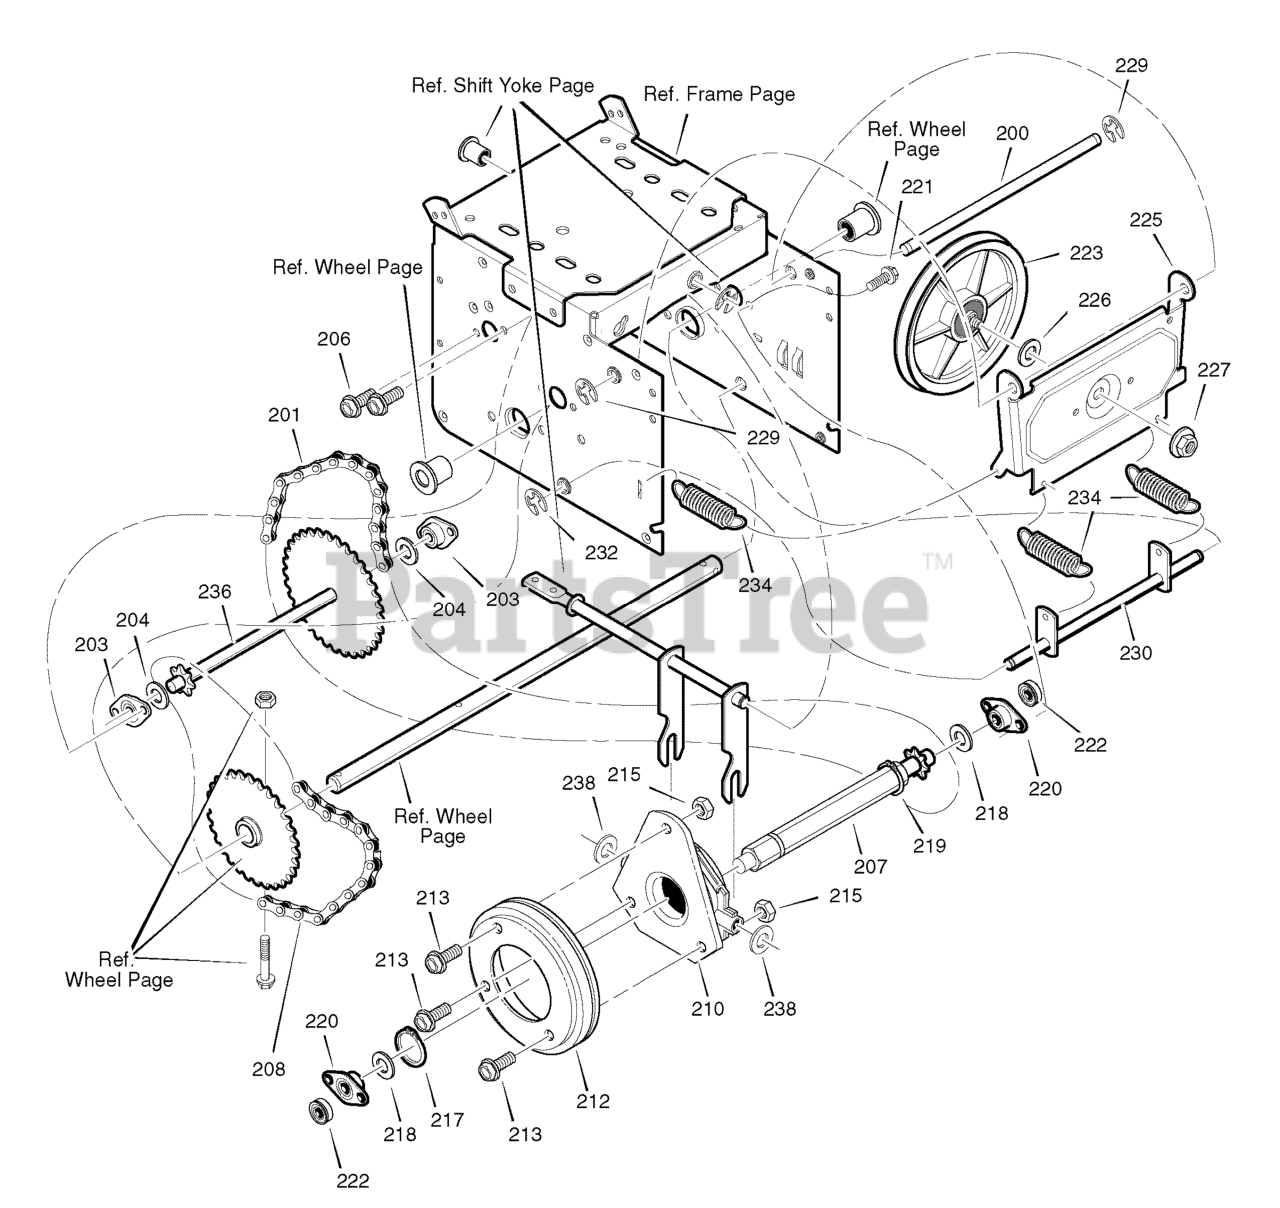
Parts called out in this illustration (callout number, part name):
200	AXLE, L.F. Swing Plate
201	CHAIN, Roller, #420 x 19
203	BEARING & RETAINER ASSEMBLY
204	WASHER
206	SCREW, Tap 5/16 - 18 x 1/2
207	HEX SHAFT ASSEMBLY
208	CHAIN, Roller, #420 x 18
210	BEARING, Trunion Clutch R.H.
212	WHEEL, Friction Disc
213	BOLT
215	NUT, Hex Keps, 1/4 - 20
217	RING, Retainer
218	WASHER
219	RING, Snap
220	BEARING & RETAINER ASSEMBLY
221	SCREW, Tap 5/16 - 18 x 1/2
222	BEARING, Ball
223	FRICTION PULLEY
225	PLATE, L.F. Swinging
226	SPACER, Friction Pulley
227	NUT, Flange Lock, 3/8 - 24
229	RETAINER, Ring
230	SPRING LINK ASSEMBLY, L.F.
232	RETAINER, Ring
234	SPRING, Extension
236	SPROCKET, 33/7
238	WASHER, Flat
